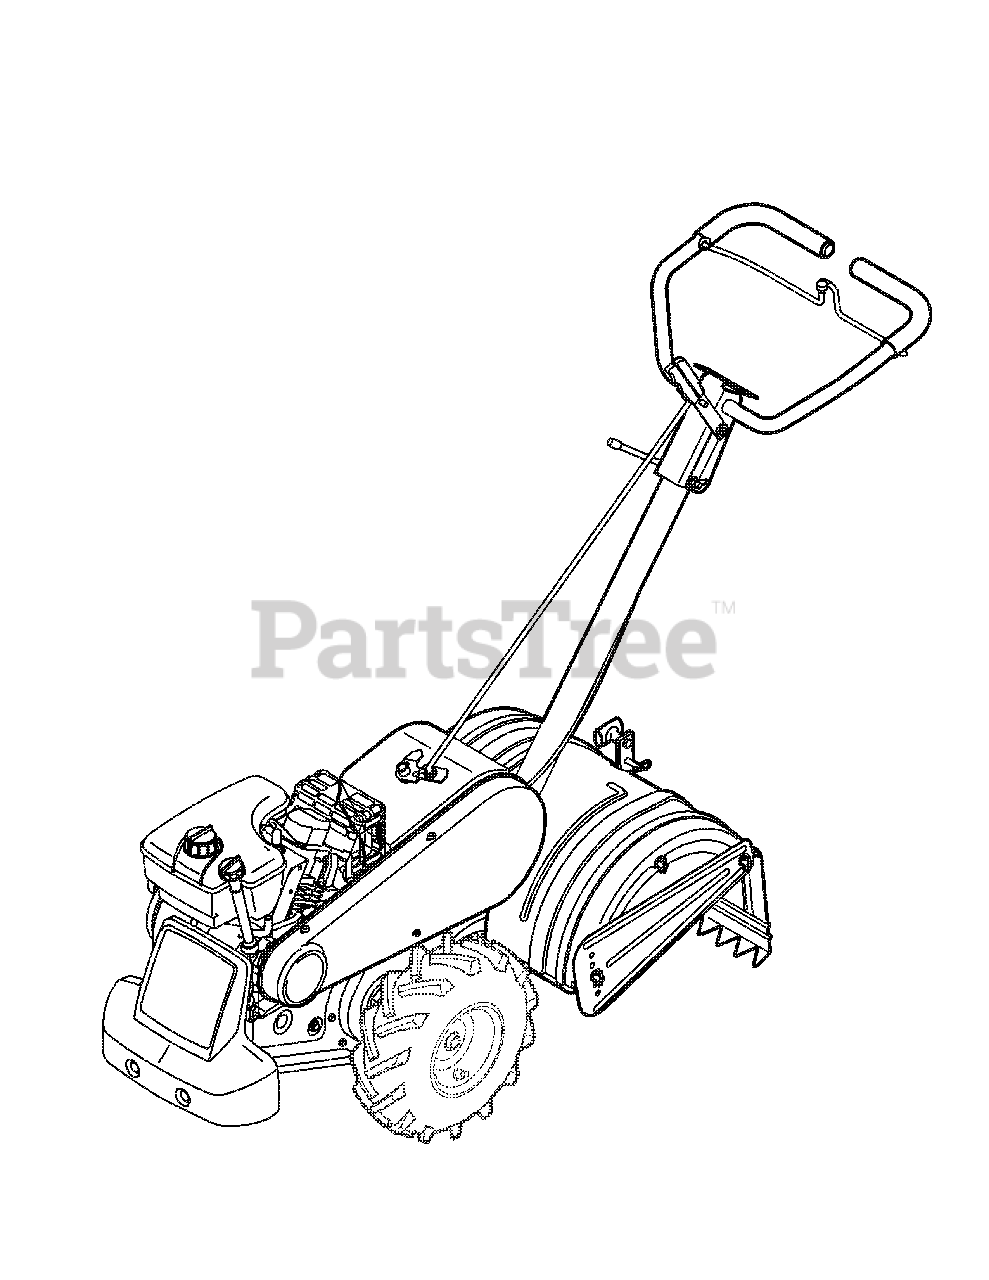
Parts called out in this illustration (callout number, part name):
NA	Drive Belt
NA	Clutch Cable
NA	Rim
